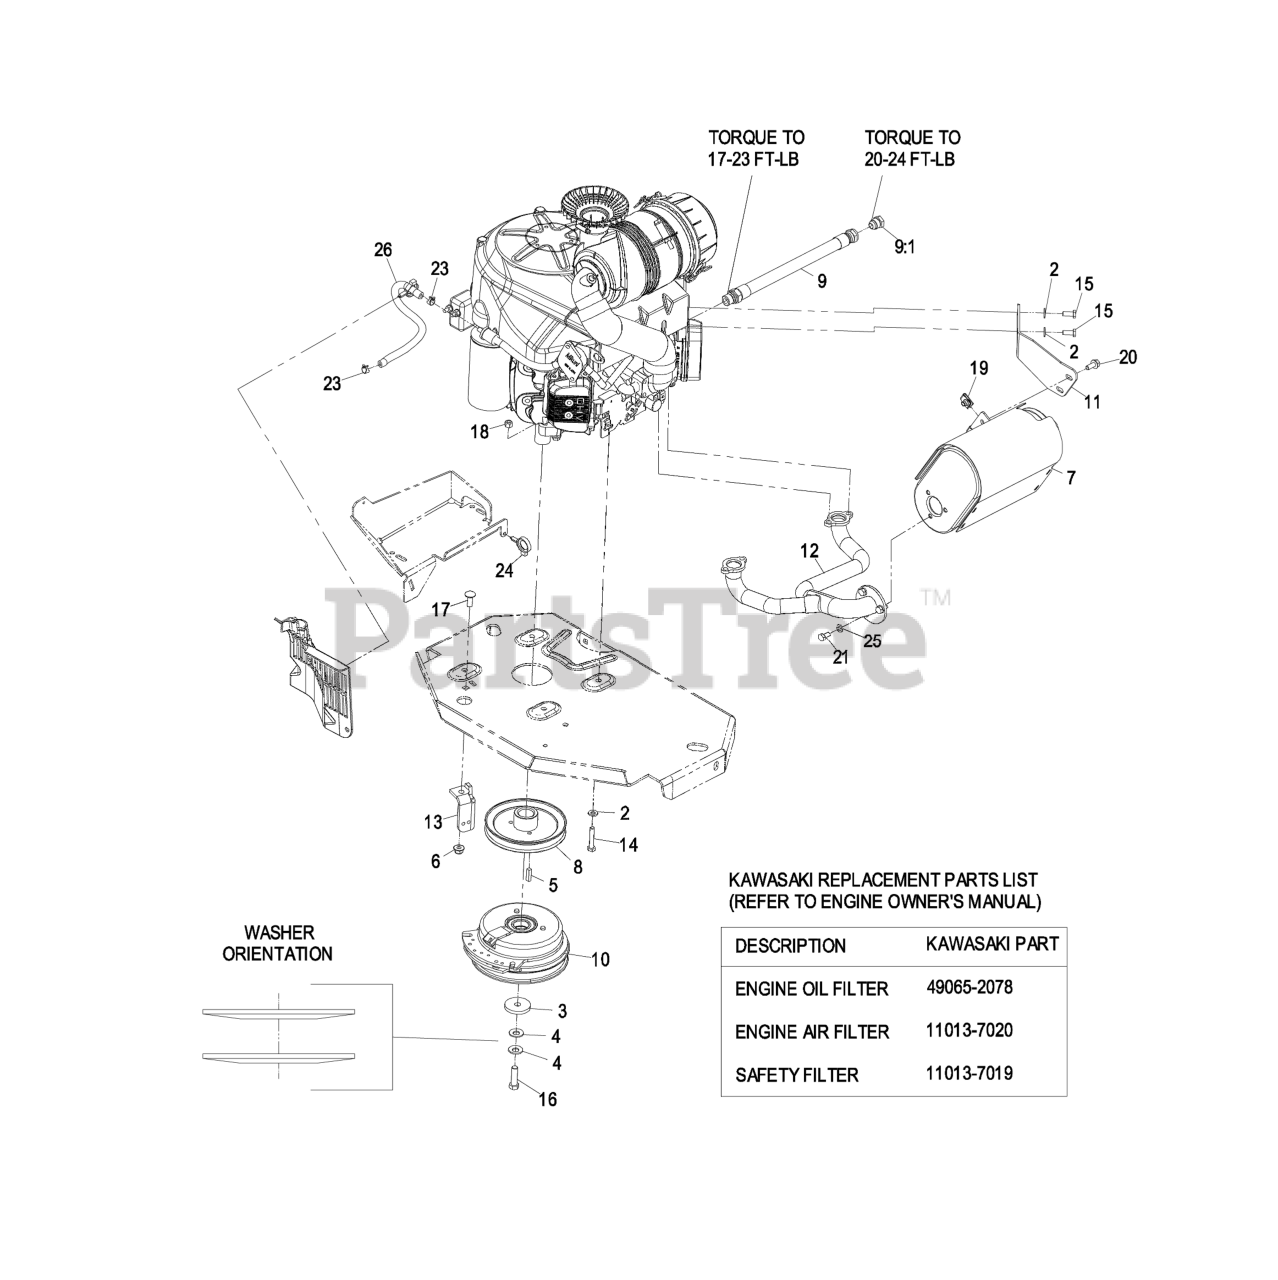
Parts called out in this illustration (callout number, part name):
2	WASHER-SPRING
3	WASHER-CLUTCH
4	WASHER-SPRING
6	NUT-HF, NI
7	MUFFLER-ENGINE
8	SHEAVE
12	MANIFOLD-EXHAUST
13	ANCHOR-CLUTCH
14	SCREW-HH
15	SCREW-HH
16	SCREW-HH 7/16-20 X 1 1/2 W/LOCTITE
17	SCREW-CARR
18	NUT-LOCK, NI
20	SCREW-HHF
21	SCREW-HH
23	CLAMP-HOSE
24	CLAMP-HOSE
25	WASHER-LOCK
26	HOSE-FUEL
